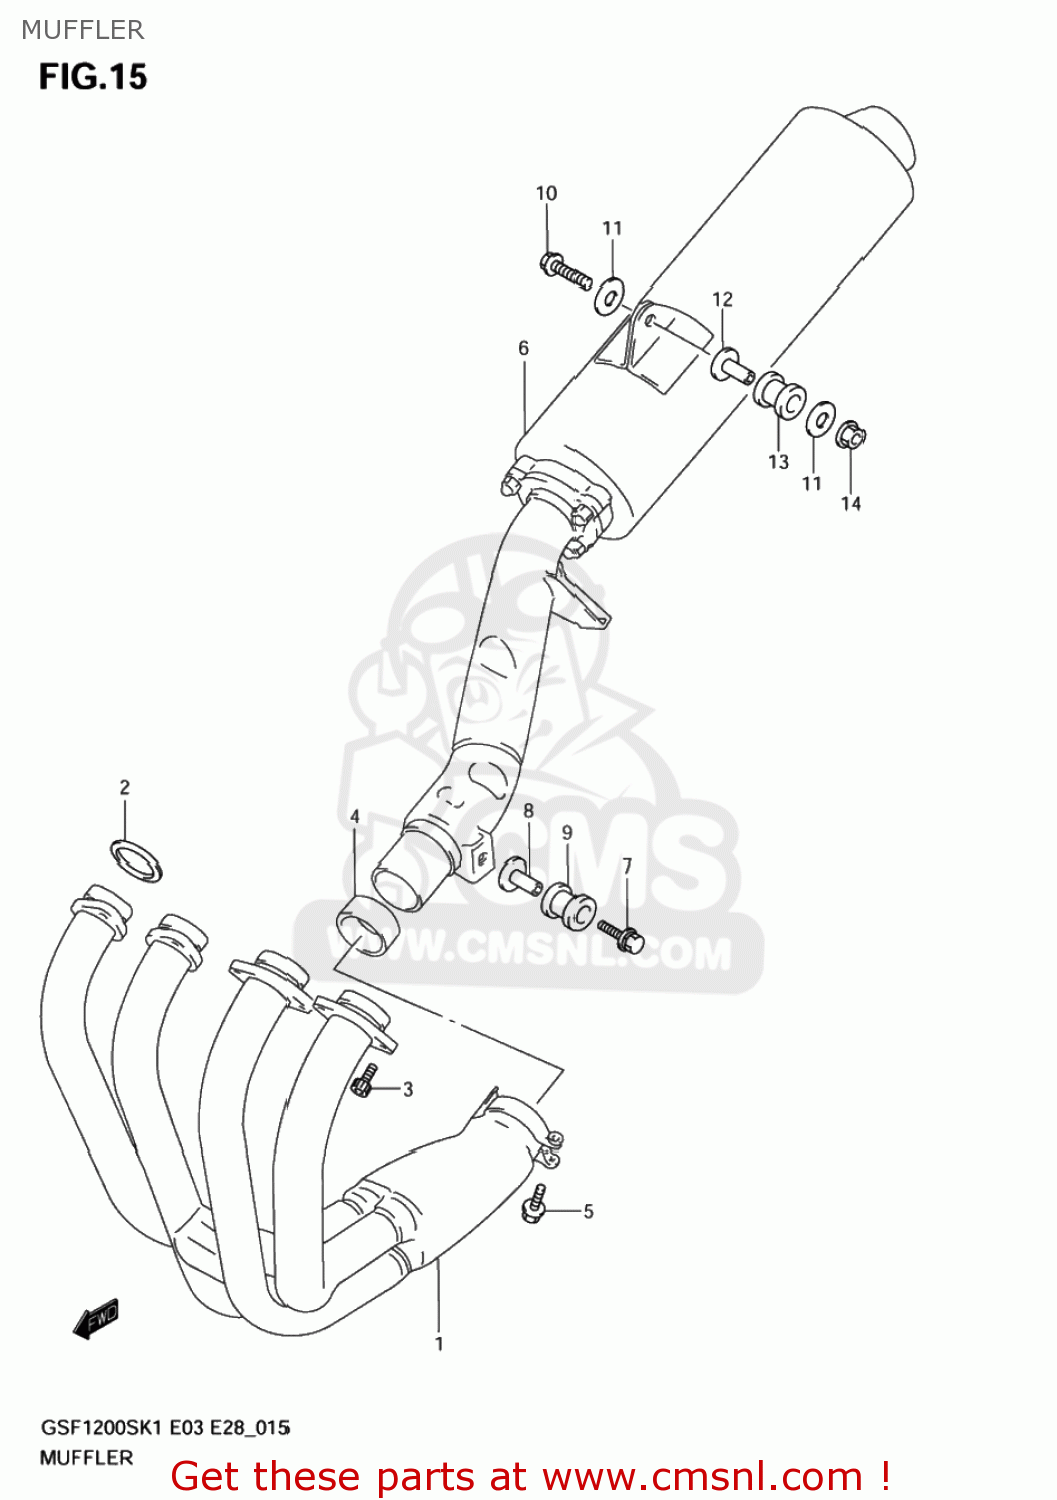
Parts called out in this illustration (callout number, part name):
1	EXHAUST COMP
2	GASKET,EXHAUST (NAS)
3	BOLT(8X25)
4	CONNECTOR,MUFFLER
5	BOLT
6	MUFFLER
7	BOLT 8X40
8	SPACER(8.6X12X24.2)
9	CUSHION
10	BOLT(8X50)
11	WASHER (8.5X33X1.6)
12	SPACER(8.5X12X30.1)
13	CUSHION
14	NUT
